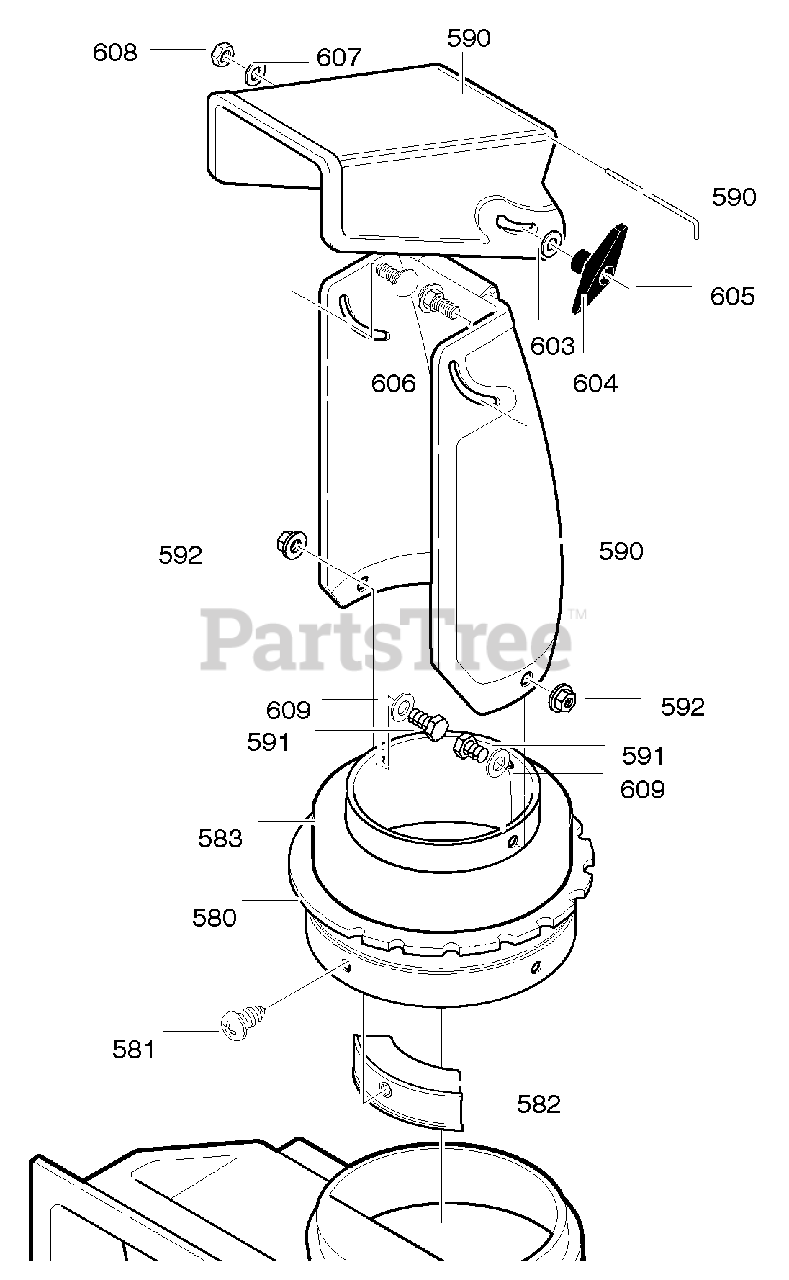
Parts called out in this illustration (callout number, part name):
580	RING, CHUTE
581	SCREW, #10X.50
582	GUIDE, CHUTE
583	DONUT FOAM
590	CHUTE ASSY.
591	SCREW 1/4-20X.50
592	NUT, 1/4-20
602	BOLT, 5/16-18X1.25 CARR.
603	WASHER, FLAT
604	KNOB, T
605	NUT, 5/16-18
606	SCREW, 5/16-18 x 0.75
607	WASHER, FLAT .349X.69X.066
608	NUT, 5/16-18
609	WASHER, FLAT
